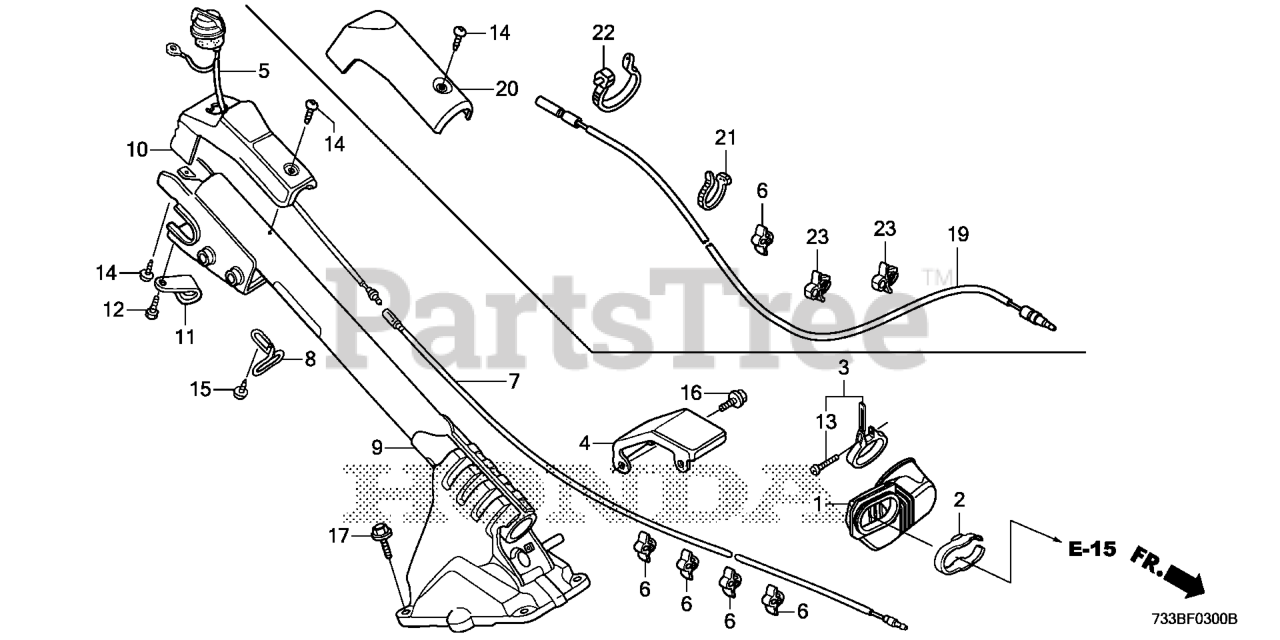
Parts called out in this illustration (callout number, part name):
1	HOSE, AIR CLEANER
2	CLIP, AIR CLEANER HOSE
3	BAND ASSY., AIR CLEANER HOSE
4	COVER, CHANGE
6	HOLDER, STOP SWITCH WIRE
8	GUIDE, CABLE
9	COLUMN, HANDLE
13	SCREW, PAN (4X30)
14	SCREW, TAPPING (5X12)
15	SCREW, TAPPING (5X10)
16	BOLT, FLANGE (6X10)
17	BOLT, FLANGE (8X16) Use from Engine SN 1000016.
19	WIRE, ENGINE STOP
20	COVER, HANDLE COLUMN
21	BAND, HARNESS (BLACK)
22	BAND, SUCTION HOSE (BLACK)
23	CLIP, CABLE (A)
